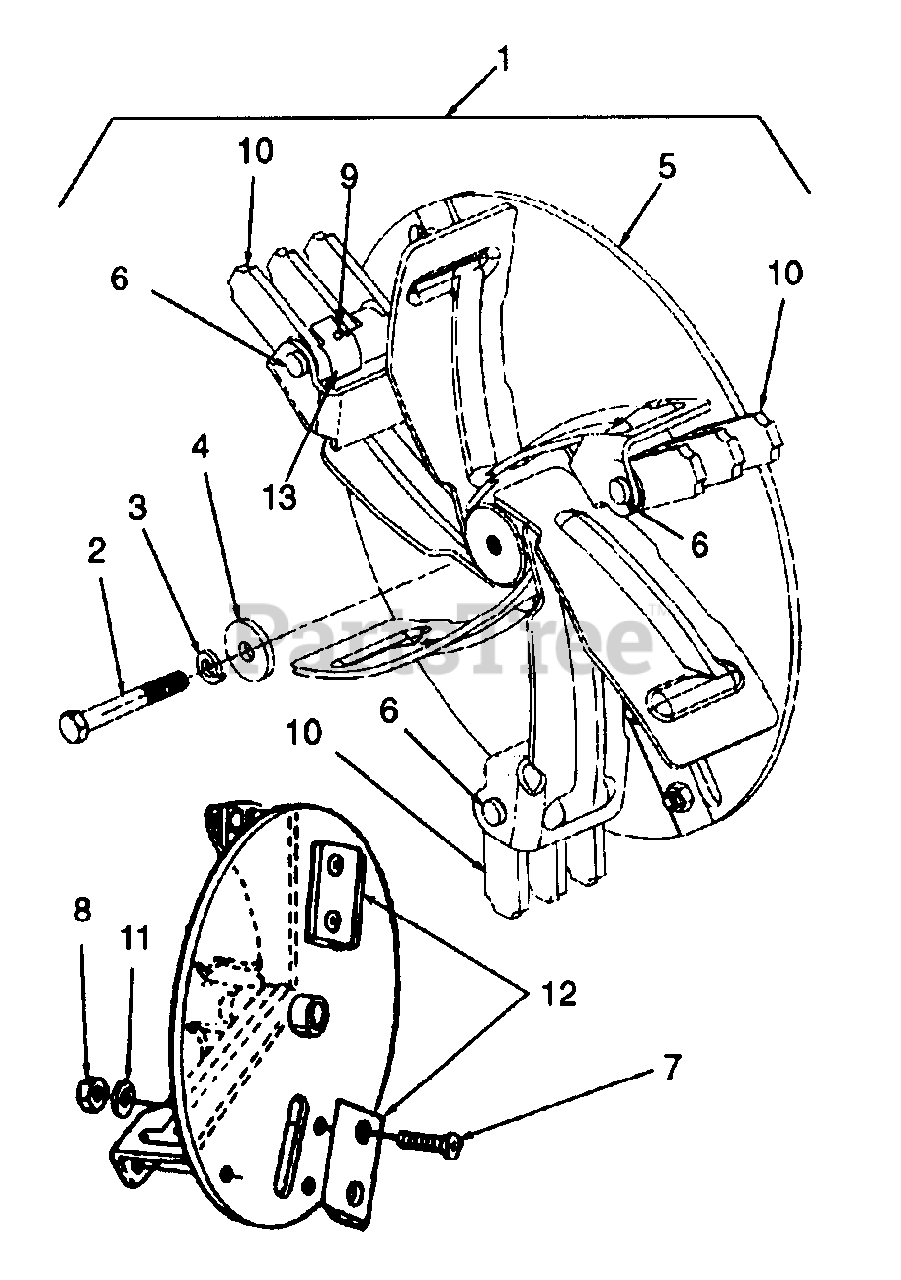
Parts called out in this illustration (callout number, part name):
1	Impeller Ass'y, Complete
2	Screw, Hex Cap, 3/8-24 x 2.75 GR5
3	Washer, Lock, 3/8 Heavy Duty 1
4	Washer, Flat, .406 x 1-1/4 HD1
5	Impeller Assembly
6	Pin, Clevis
7	Screw, Flat Hd. Cap, 5/16-24 x 1.0
8	Nut, Hex Insert Lock, 5/16-24
9	Pin, Spirol, 5/32 x 1.125
10	Blade, Flail
11	Washer, Lock, 5/16
12	Blade, Chipper
13	Pin Retaining Clip
